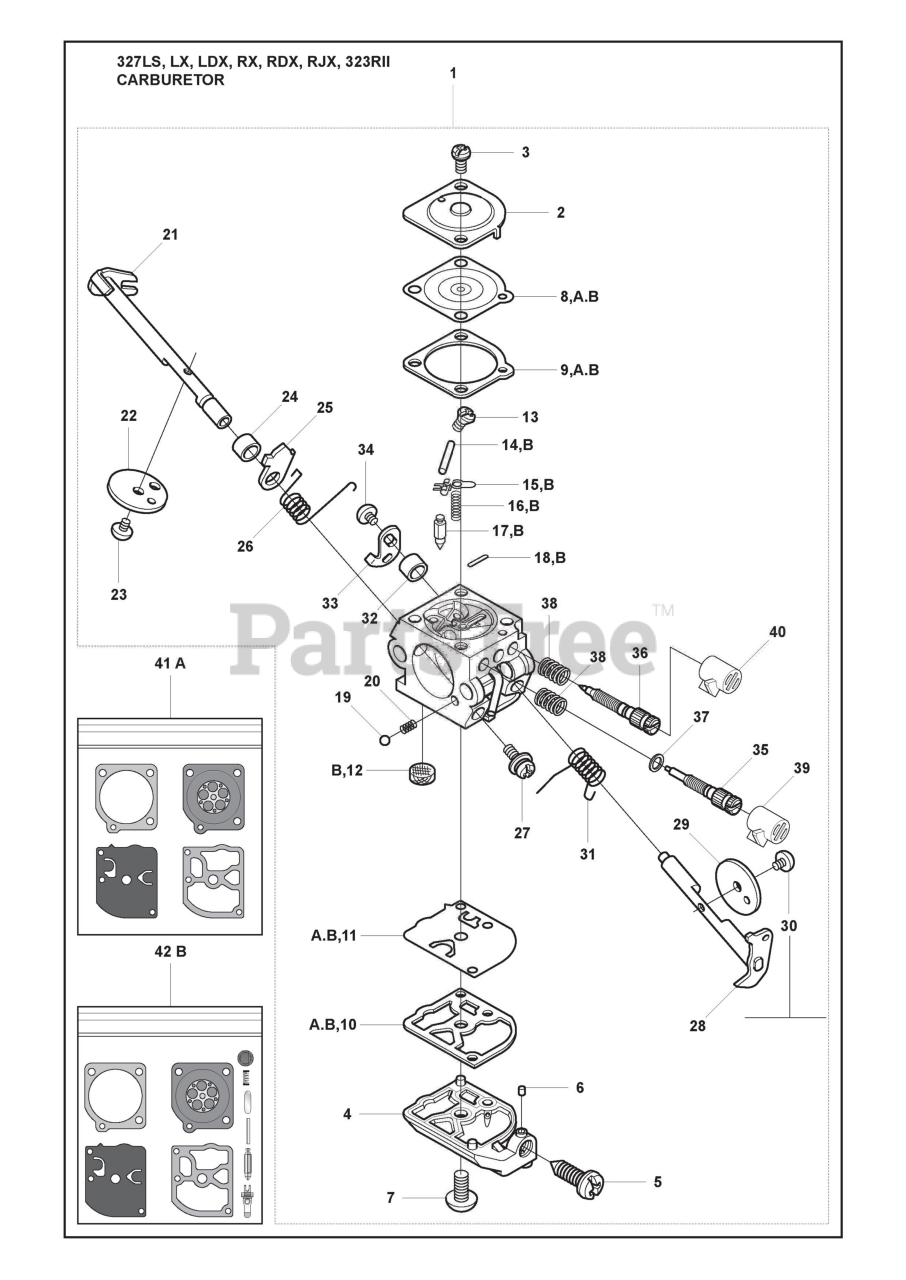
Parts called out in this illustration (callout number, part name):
1	CARBURETOR
11	PUMP DIAPHRAGM
14	PIN FULCRUM
16	SPRING
17	INLET NEEDLE
29	THROTTLE FLAP
31	SPRING THROTTLE
35	NEEDLE HIGH SPEED
36	LOW SPEED NEEDLE
38	SPRING
41A	GASKET KIT (ZAMA GND39)
42B	CARBURETOR KIT (ZAMA RB69)
